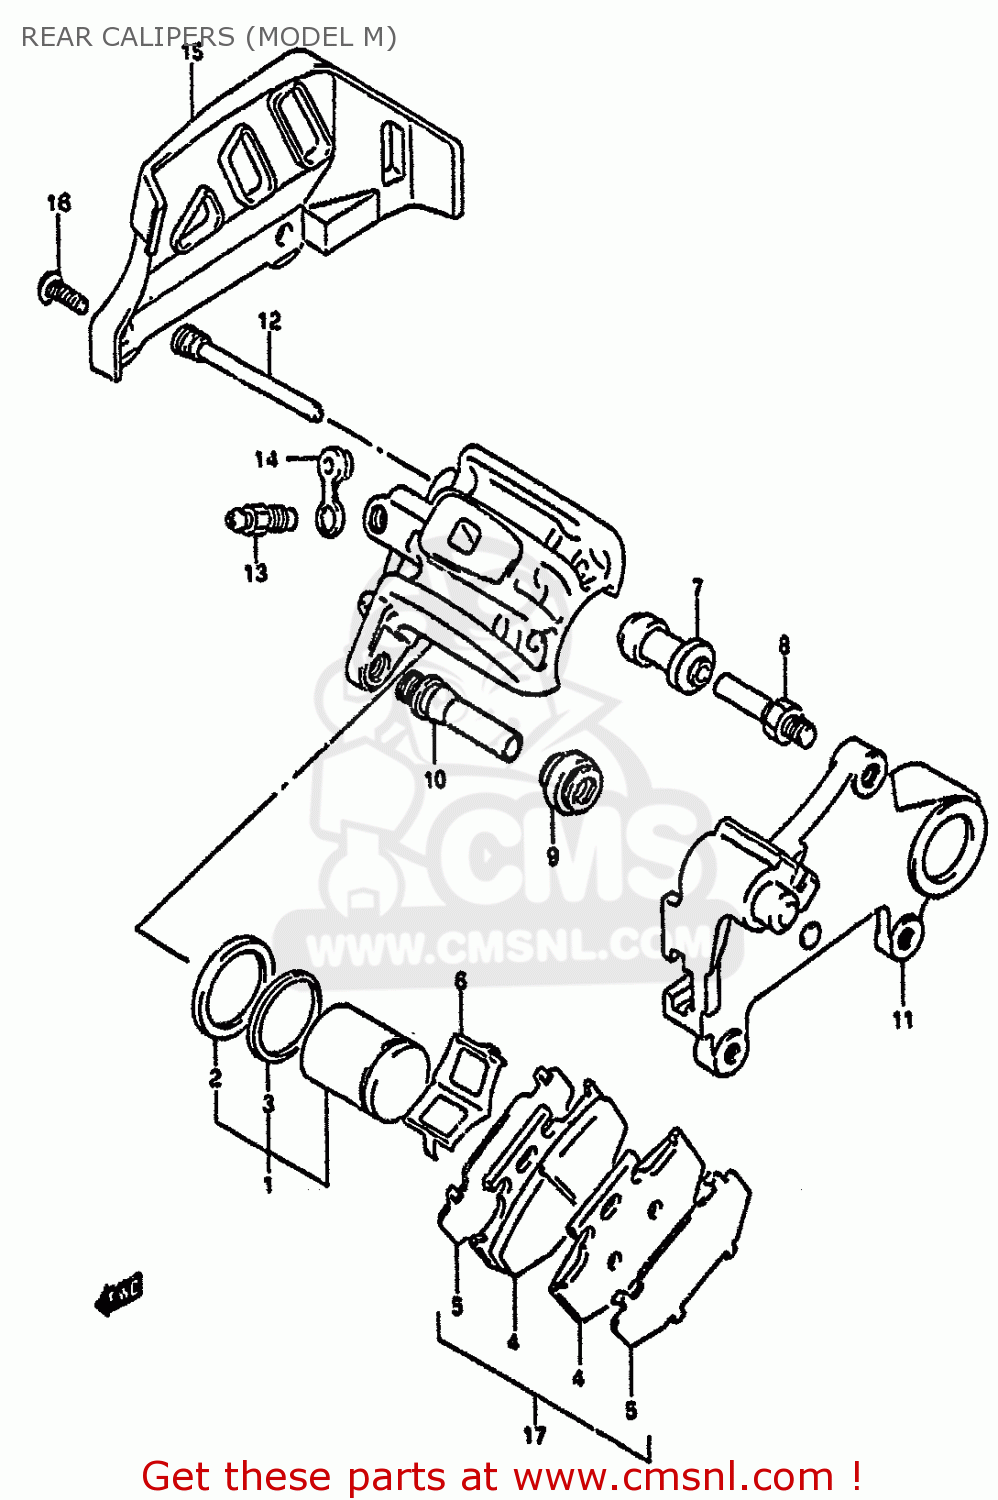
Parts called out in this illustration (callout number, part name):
1	PISTON SET
2	SEAL,PISTON
3	SEAL,DUST
4	PAD
5	SHIM
6	SPRING,PAD
7	BOOT
8	PIN,BOLT
9	BOOT
10	PIN
11	BRACKET
12	PIN,HANGER
13	BLEEDER
14	CAP,BLEEDER
15	GUARD,RR CALIPER
16	SCREW(6X12)
17	PAD SET,RR CALIPER(STRONG)
